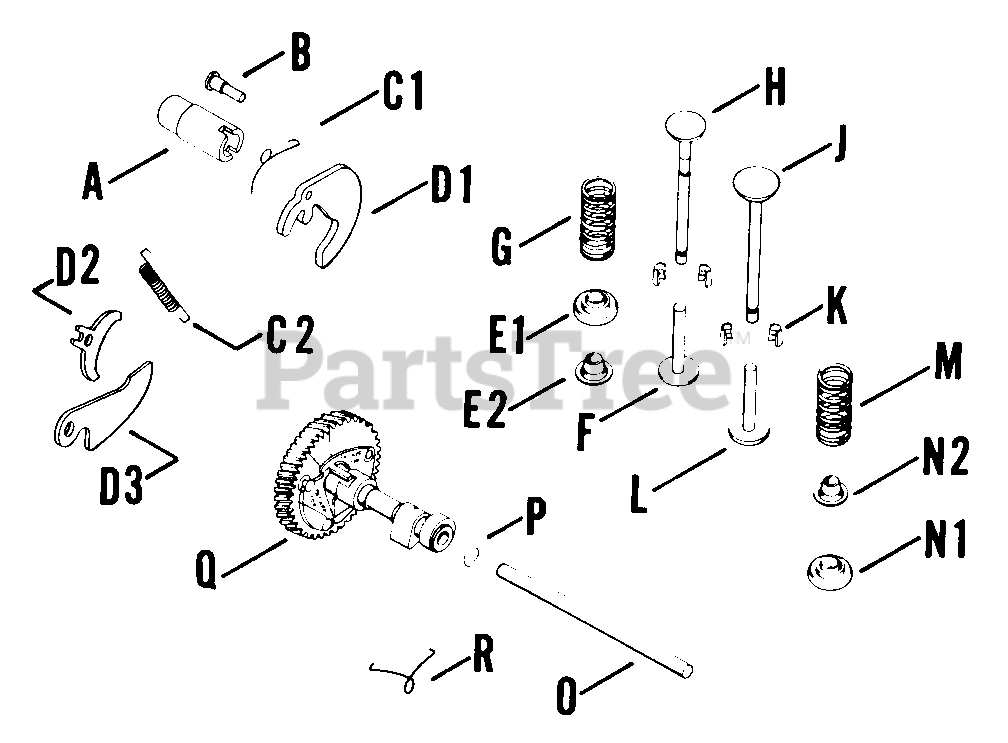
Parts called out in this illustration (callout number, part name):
A	CAM - DISCONTINUED
B	PIN - DISCONTINUED
C1	SPRING - DISCONTINUED
E2	RETAINER, VALVE SPRING
F	TAPPET
G	SPRING - DISCONTINUED
J	VALVE - DISCONTINUED
L	TAPPET - DISCONTINUED
M	SPRING - DISCONTINUED
N2	RETAINER, VALVE SPRING
O	PIN - USE 41 380 03
Q	KIT, CAMSHAFT
R	SPRING - USE 47 089 01
